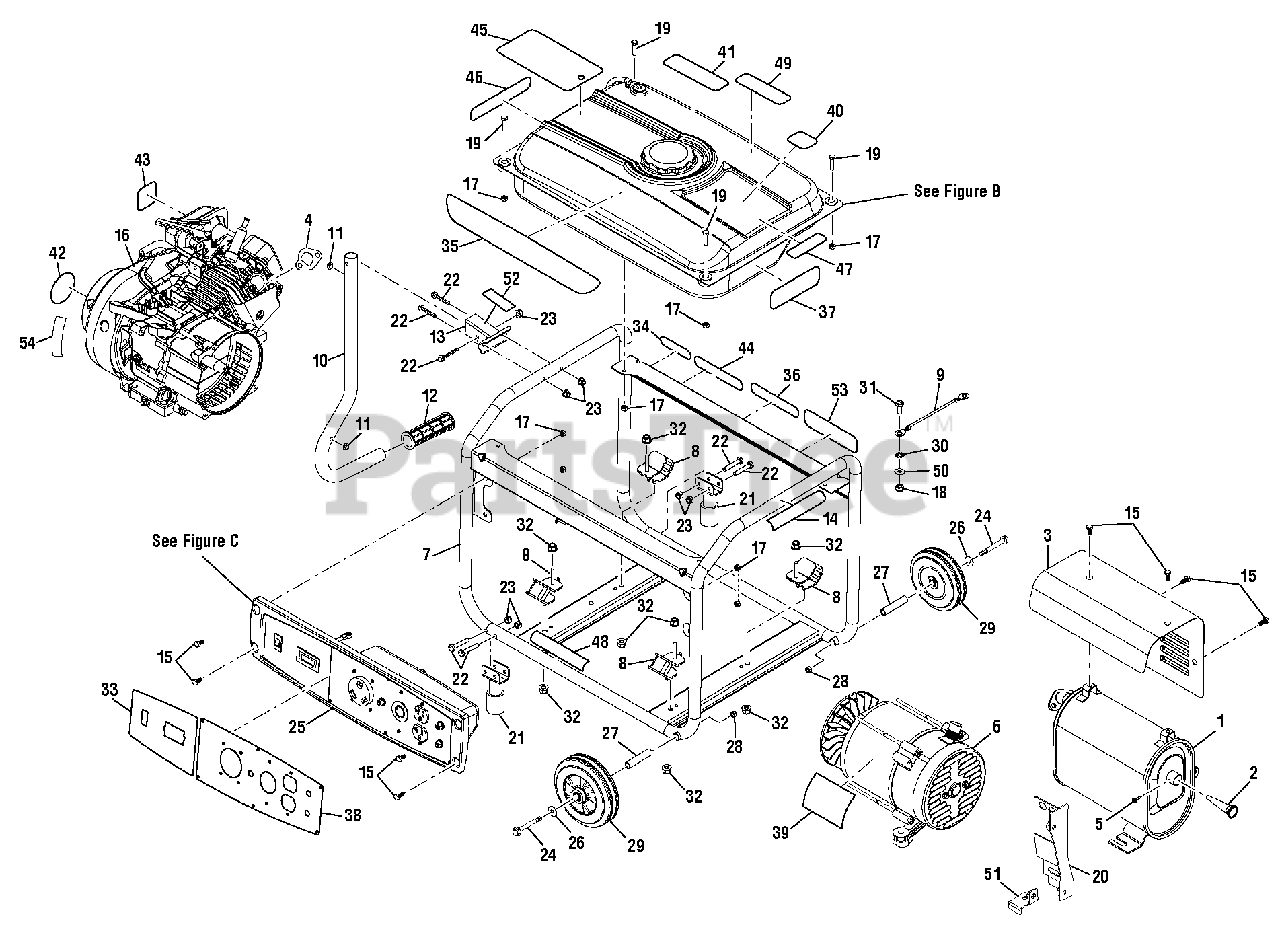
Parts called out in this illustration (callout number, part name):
2	Spark Screen
3	Heat Shield
4	Exhaust Gasket
5	Set Screw (Spark Arrestor)
6	Generator Head Assembly
7	Carrier Assembly
8	Isolators (45deg)
9	Ground Wire Assembly
10	Handle Assembly
11	Handle Bumper
12	Handle Grip
13	Handle Bracket
14	Fire Distance Label
15	Screw (M6 x 14 mm)
17	Lock Nut (M6)
18	Lock Nut (5/16-18)
19	Bolt (M6 x 20 mm, Hex Hd.)
20	Muffler Bracket
21	Foot Assembly
22	Bolt (1/4-20 x 1.5 in.)
23	Lock Nut (1/4-20)
24	Bolt (3/8-16 x 4.25 in.)
25	Panel Assembly
26	Washer (3/8 in.)
28	Lock Nut (3/8-16)
29	Wheel (7 in.)
30	Star Washer (5/16 in.)
31	Bolt (5/16-18 x 19 mm)
32	Flange Nut (M8)
33	Control Panel Label (Left)
34	Homelite Label
35	Logo Label
36	Hot Surface Label
37	Combustion Label (Eng/Fr/Sp)
38	Control Panel Label (Right)
39	Data Label
40	E85 Label
41	CPSC Label
42	Recoil Housing Label
43	Choke Label
44	Ground Warning Label
45	Danger hangtag
46	Engine Start Label
47	Fire Danger Label
48	Lubricant Label
49	Warning Label
50	Lock Washer (5/16 in.)
51	Muffler Bracket (Gen Head)
52	Lock Pin Label
53	Homelite Click Label
54	Evaporative Label
